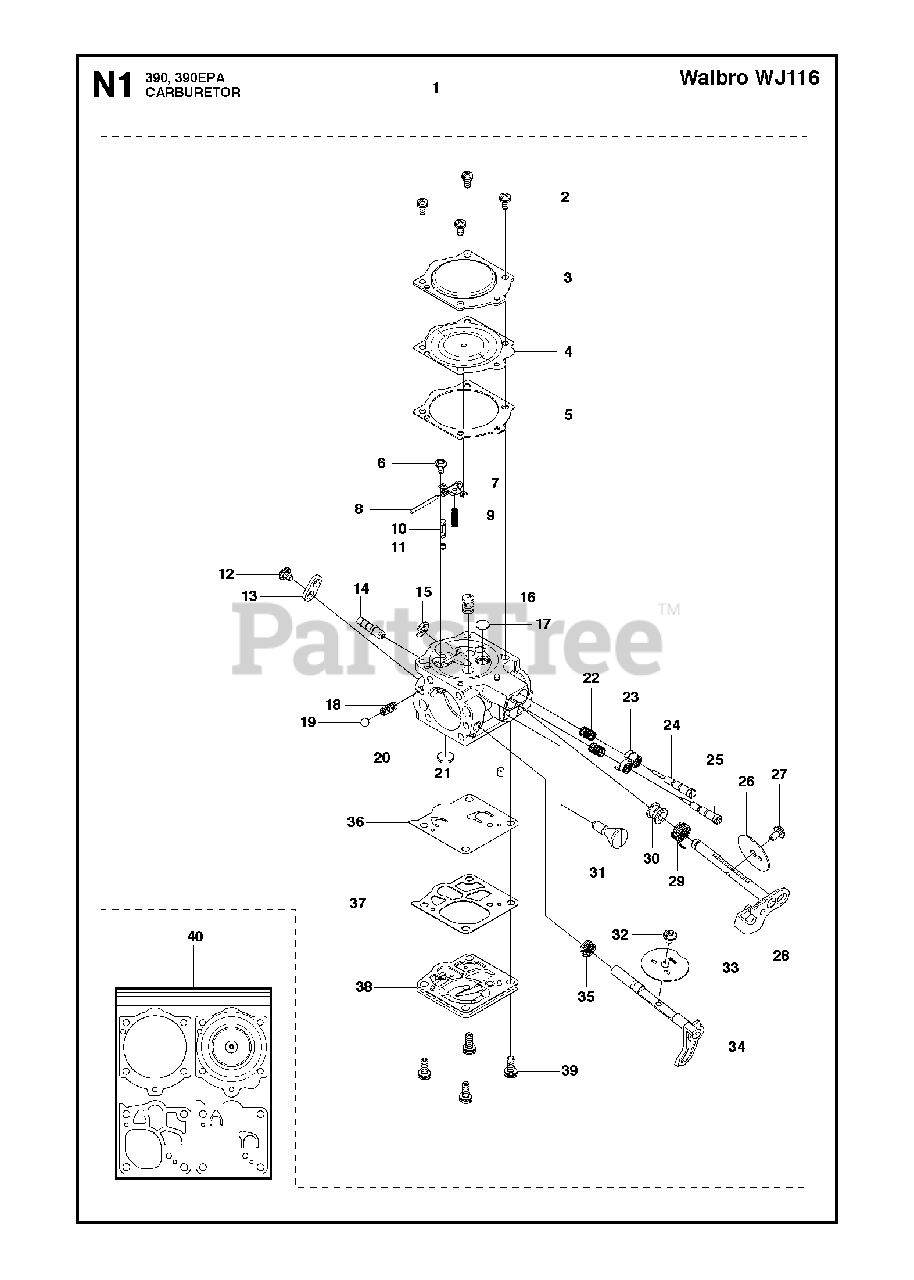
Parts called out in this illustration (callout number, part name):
1	CARBURETOR
2	RP SCREW W/ WASHER
3	DIAPHRAM COVER
4	Main Diaphragm
5	GASKET
6	SCREW
7	LEVER
8	PIN
9	SPRING
10	INLET NEEDLE
11	SEAT IN VALVE PLATED
12	SCREW
13	LEVER CHOKE
14	FITTING FUEL INLET
15	E CLIP
16	NOZZLE
17	PLUG WELCH
18	SPRING
19	BALL 394
20	FUEL INLET SCREEN
21	PLUG FRICTION
22	SPRING
23	LIMITER CAP
24	NEEDLE
25	NEEDLE
26	THROTTLE FLAP
27	SCREW
28	SHAFT ASSY THROTTLE
29	SPRING
30	BUSHING
31	SCREW
32	SCREW
33	CHOKE FLAP
34	SHAFT ASSY
35	SPRING CHOKE
36	DIAPHRAM PUMP
37	GASKET
38	COVER PUMP
39	SCREW W/ WASHER
40	DIAPHRAGM SET
